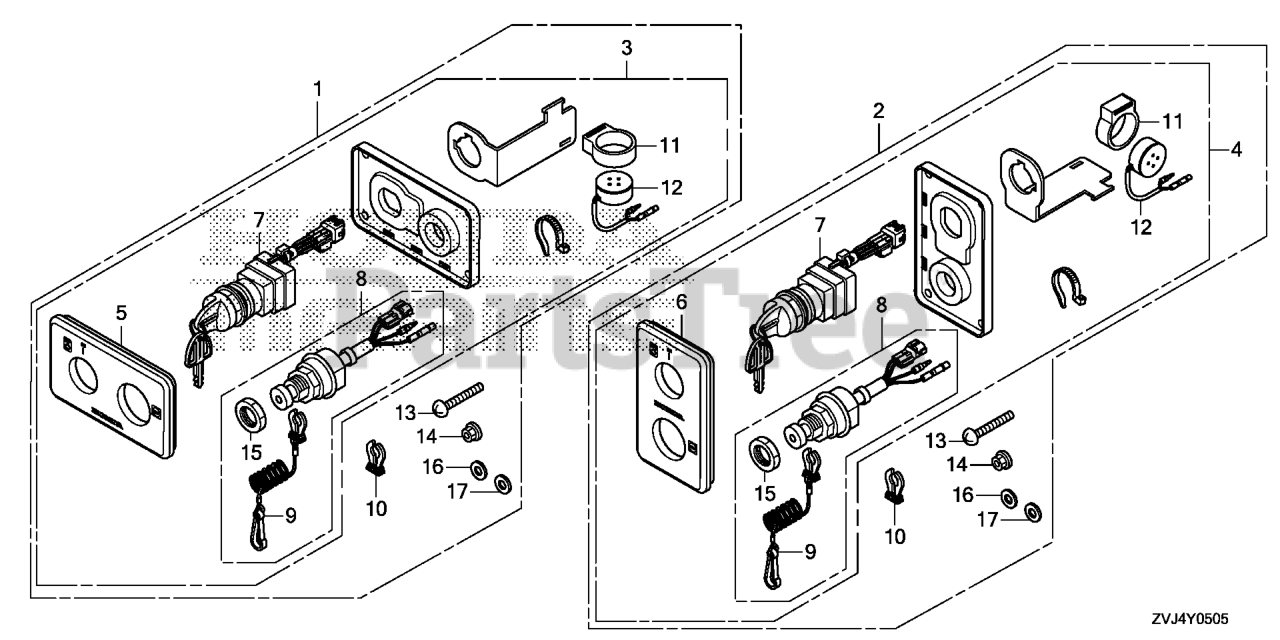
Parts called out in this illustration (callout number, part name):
1	PANEL KIT, KEY SWITCH (START)
1	PANEL KIT, KEY SW
1	PANEL KIT, KEY SWITCH
2	PANEL KIT, KEY SWITCH
2	PANEL KIT, KEY SW
2	PANEL KIT, KEY SWITCH (START)
3	PANEL ASSY., KEY SWITCH (START)
3	PANEL ASSY., KEY SW
3	PANEL ASSY., KEY SWITCH
4	PANEL ASSY., KEY SWITCH
4	PANEL ASSY., KEY SW
4	PANEL ASSY., KEY SWITCH (START)
5	PANEL, KEY SWITCH (START)
5	PANEL, KEY SWITCH
6	PANEL, KEY SWITCH
6	PANEL, KEY SWITCH (START)
7	SW ASSY., COMB
7	SWITCH ASSY., COMBINATION
8	SWITCH ASSY., EMERGENCY STOP
9	WIRE, EMERGENCY
10	CLIP, EMERGENCY LOCK
11	SUSPENSION, AUDIBLE PILOT
12	BUZZER, WARNING
13	SCREW, PAN (5X40) DUAL QTY = (8) (SINGLE)
14	NUT, FLANGE (5MM)
15	NUT
16	WASHER, PLAIN (5MM)
17	WASHER, SPRING (5MM)
17	WASHER, SPG (5MM)
